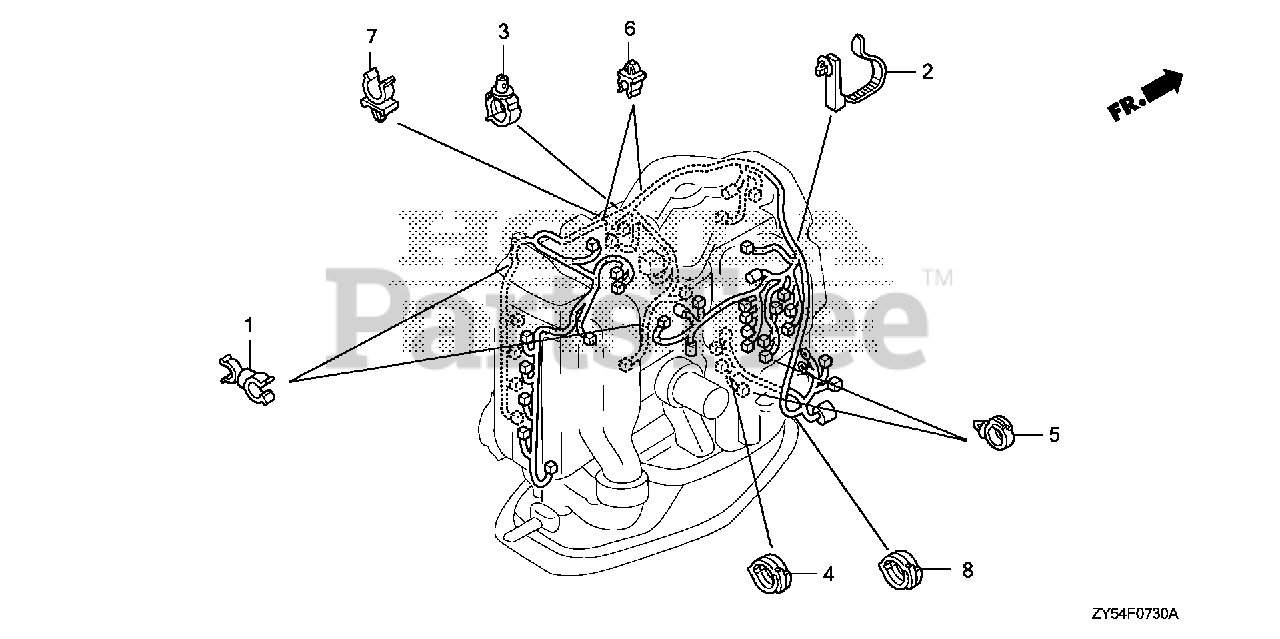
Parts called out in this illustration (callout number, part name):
1	CLAMP, HOSE
2	BAND, HARNESS OFFSET (10) (122.5MM) (BROWN)
3	CLAMP, ENGINE SUB-WIRE
4	CLIP, WIRE HARNESS
5	CLIP, WIRE HARNESS (25MM)
6	CLIP, TUBE (3.5)
7	CLAMP (18.5MM)
8	CLIP, WIRE HARNESS
